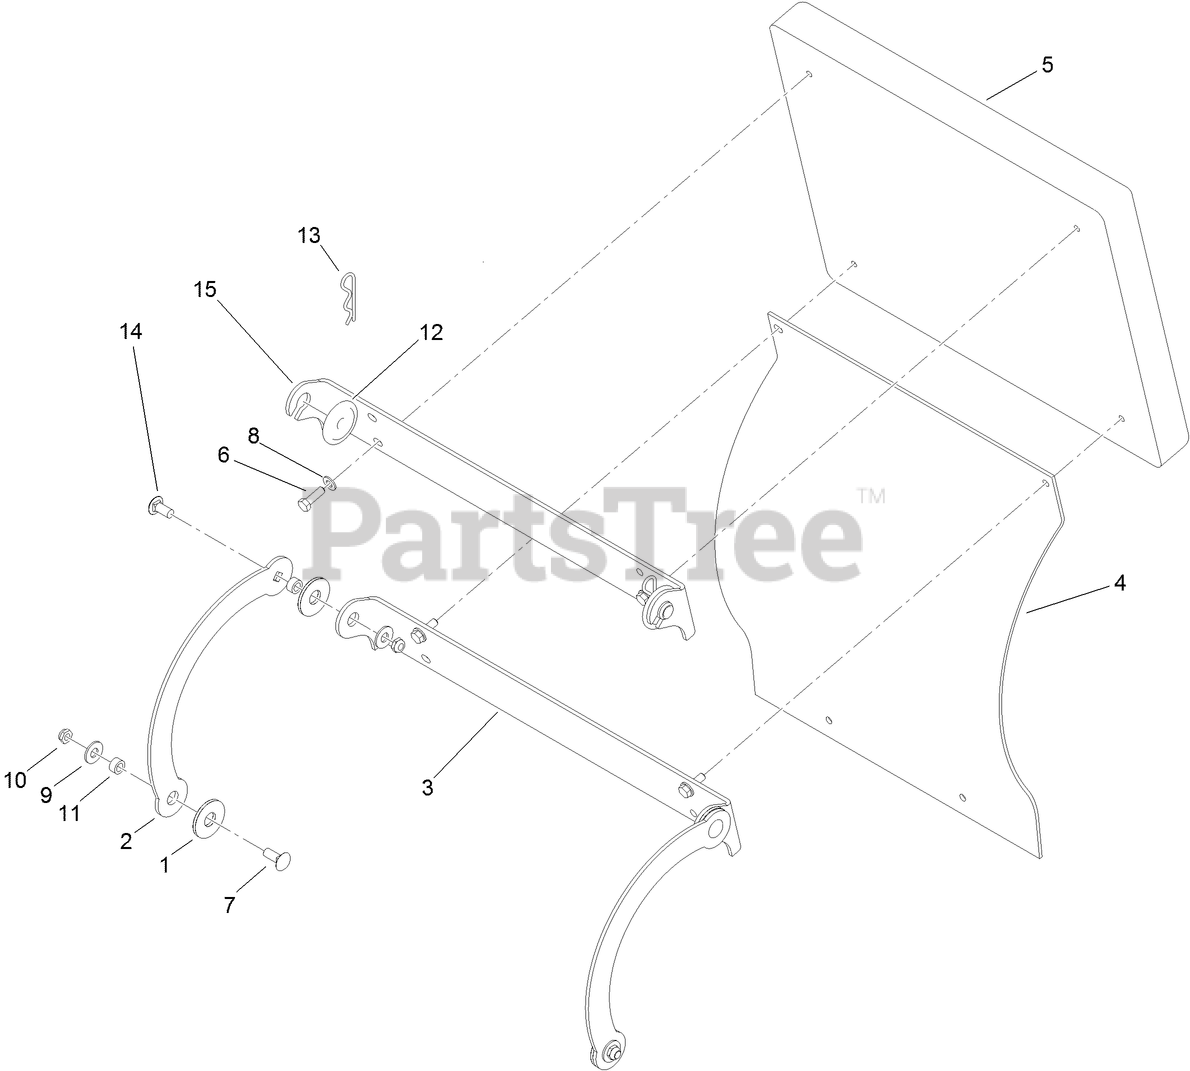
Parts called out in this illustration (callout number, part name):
1	WASHER-FRICTION, COMPOSITE
2	LINK-PAD
3	HINGE-PAD
4	SHIELD-REAR
5	PAD-CUSHION
6	SCREW-HH
7	BOLT-CARR
8	WASHER-PLAIN
9	WASHER-FLAT
10	NUT-LOCK, NI
11	SPACER
12	SLIDE-BUSHING
13	PIN-HAIR
14	SCREW-CARR
15	HINGE-PAD
